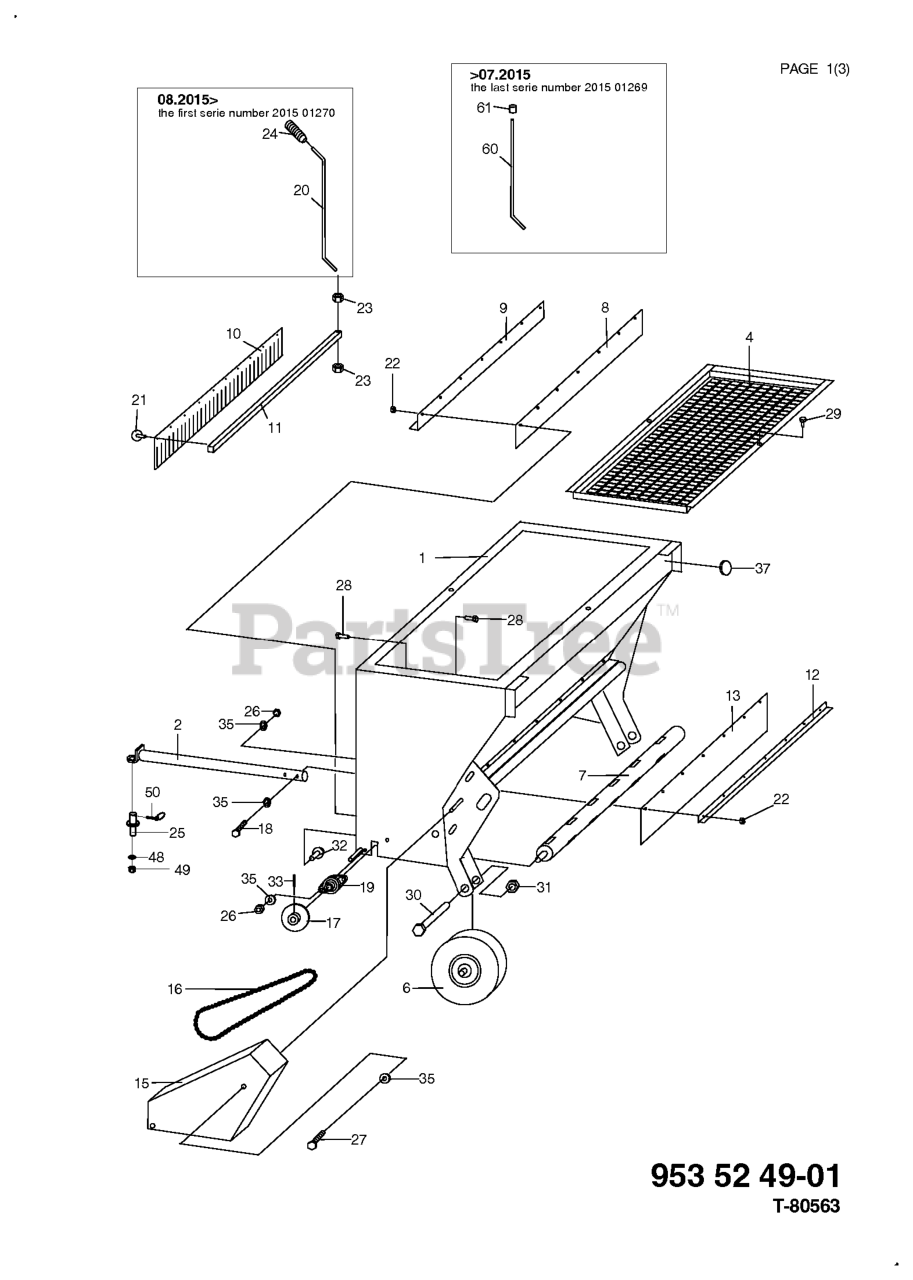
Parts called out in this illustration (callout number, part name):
19	BEARING UCFL 204
24	GEAR STICK KNOB
32	SCREW, LOCK
